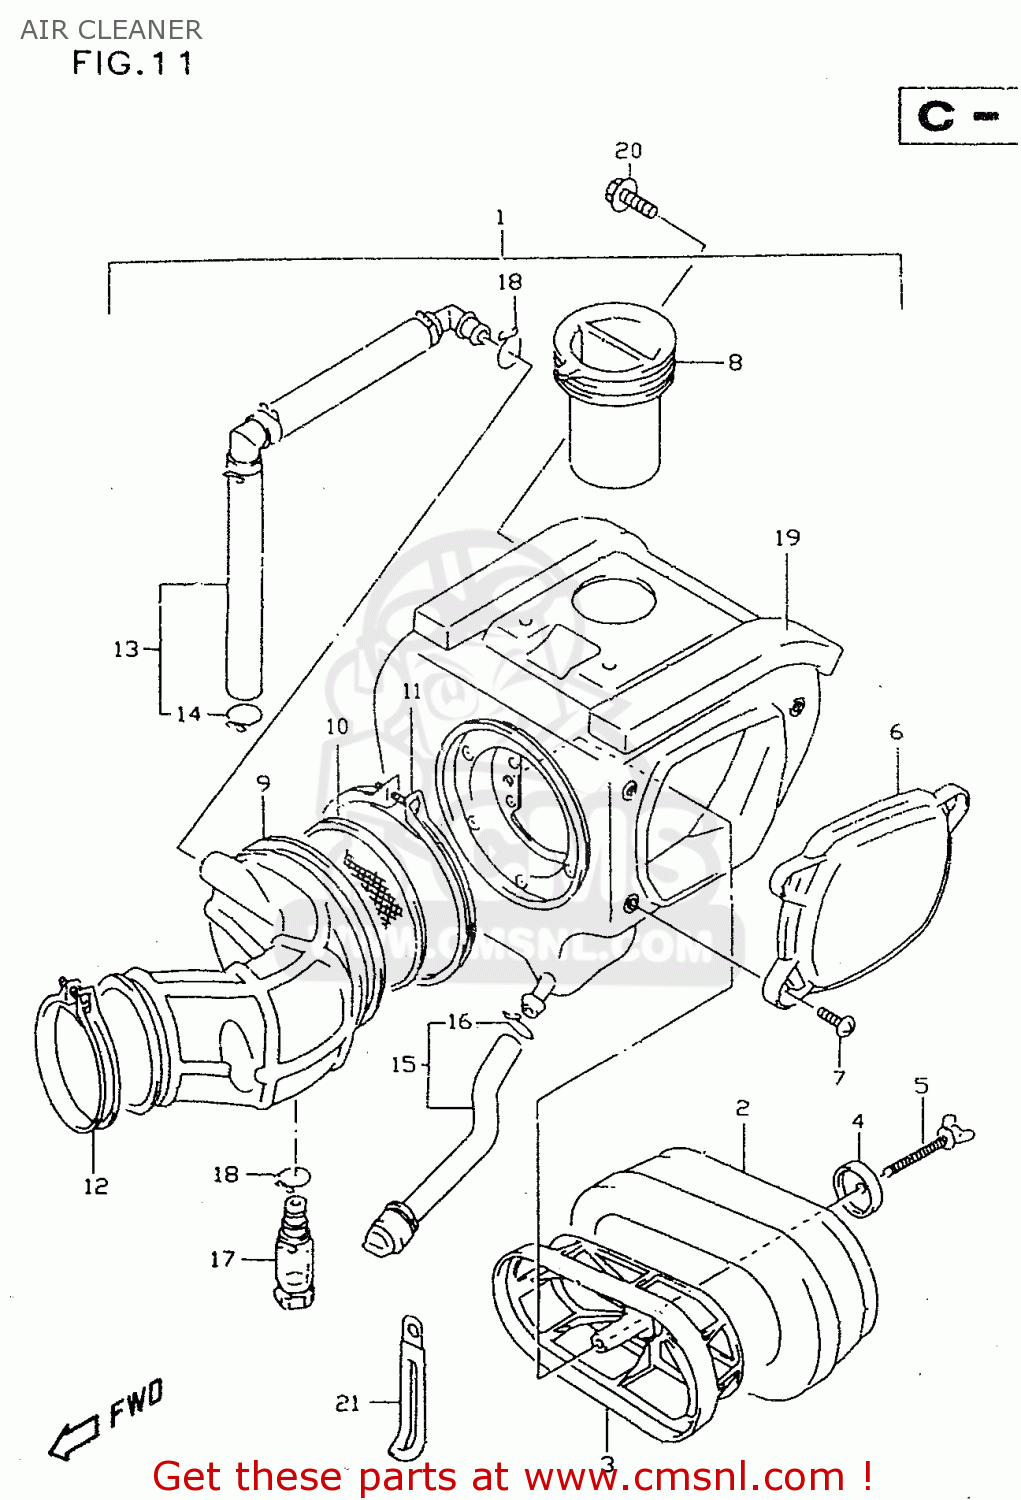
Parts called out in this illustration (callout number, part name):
1	CLEANER ASSY,AIR
2	FILTER
3	HOLDER,FILTER
4	WASHER,AIR CLEANER
5	BOLT,WING
6	CAP,AIR CLEANER
7	SCREW
8	TUBE,INLET
9	TUBE,OUTLET
10	TRAP,FRAME
11	CLAMP,OUTLET TUBE
12	CLAMP
13	TUBE,BREATHER
14	CLIP
15	TUBE,DRAIN A
16	CLIP
17	TUBE,DRAIN
18	CLIP
19	CUSHION
20	BOLT
21	CLAMP
